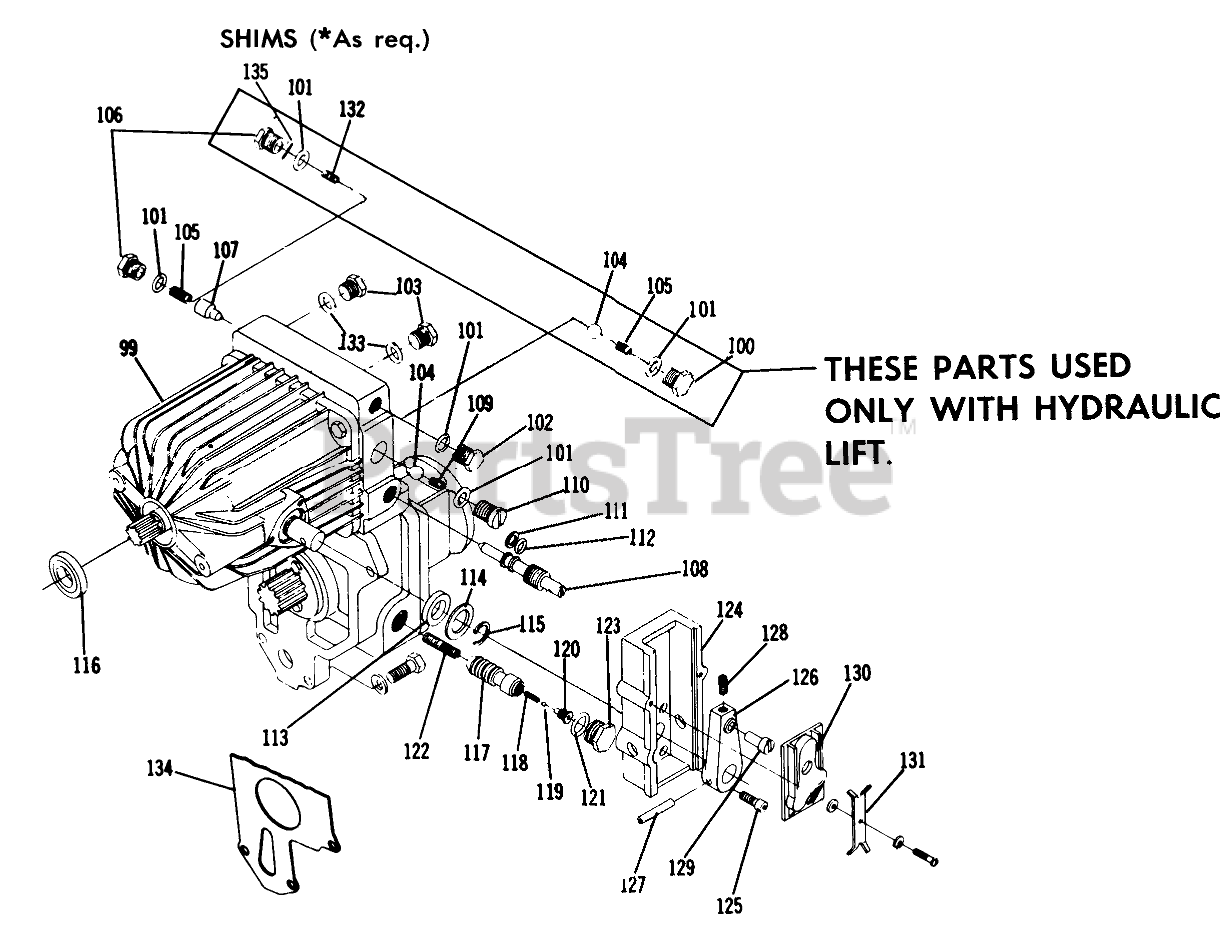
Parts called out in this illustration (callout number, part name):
4-99	Hydro Unit
4-100	Plug
4-101	O RING
4-103	Plug-Hex 9/16-18
4-104	Ball
4-105	Spring Chg. Rel. Valve
4-106	Plug
4-107	Cone
4-108	VALVE
4-109	Spring
4-110	PLUG
4-111	O-RING
4-112	Back Up Ring
4-113	SEAL
4-114	WASHER-LAMBERT
4-115	RING-LAMBERT
4-116	SEAL
4-117	Sleeve
4-118	SPRING
4-120	Valve
4-121	O-Ring
4-122	Spring
4-124	SUPPORT CAM BLOCK
4-125	SHCS 1/4-20 X 1/2
4-126	Belt Guide
4-127	PIN-ROLL 1/4 X 1 1/4
4-128	Set Screw-1/4-20 x 1/2
4-129	Eccentric-Cam Follower
4-130	CAM
4-131	TENSION PLATE
4-132	SPRING VALVE SUNSTR
4-133	0-Ring
4-134	GASKET
4-135	Shim Set
